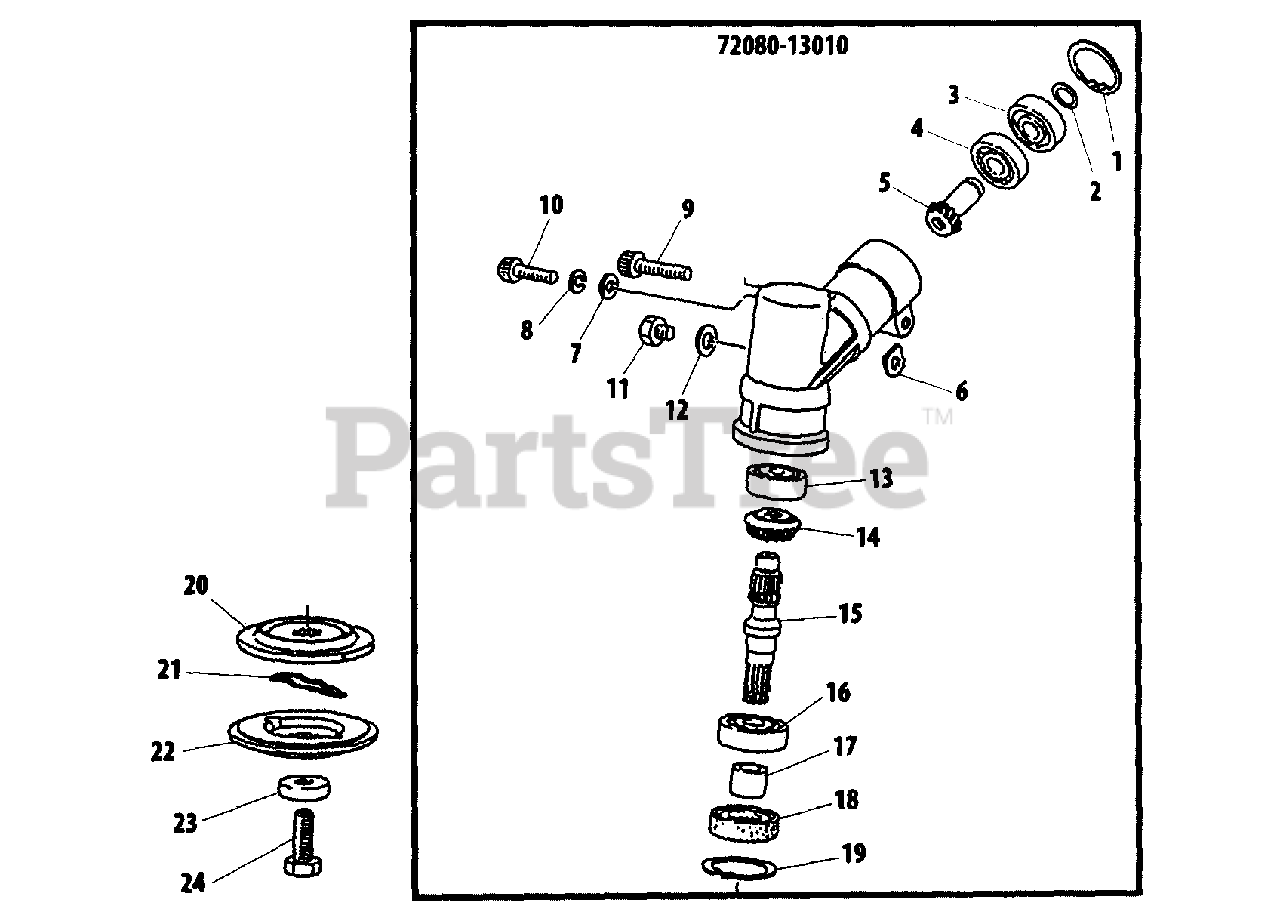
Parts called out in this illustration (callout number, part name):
1	RING, SNAP Ø28
2	RING, SNAP Ø12
3	BEARING, BALL 6001ZZ
4	BEARING, BALL 6001
5	PINION ASSY, BEVEL
6	D-WASHER
7	WASHER 6.5×11.5×0.8
8	WASHER, SPRING 6
9	BOLT M6×28
10	BOLT
11	BOLT M6×10
12	WASHER
13	BEARING, BALL 6000DDU
14	GEAR, BEVEL
15	SHAFT, GEAR
16	BEARING, BALL 6202
17	COLLAR
18	SEAL, OIL
19	RING, SNAP Ø35
20	PLATE, ADAPTOR - UPPER
21	PIN, SLIDE
22	PLATE, ADAPTOR - LOWER
23	GUARD, BOLT
24	BOLT 10×30
72080-13010	GEAR CASE ASSY
